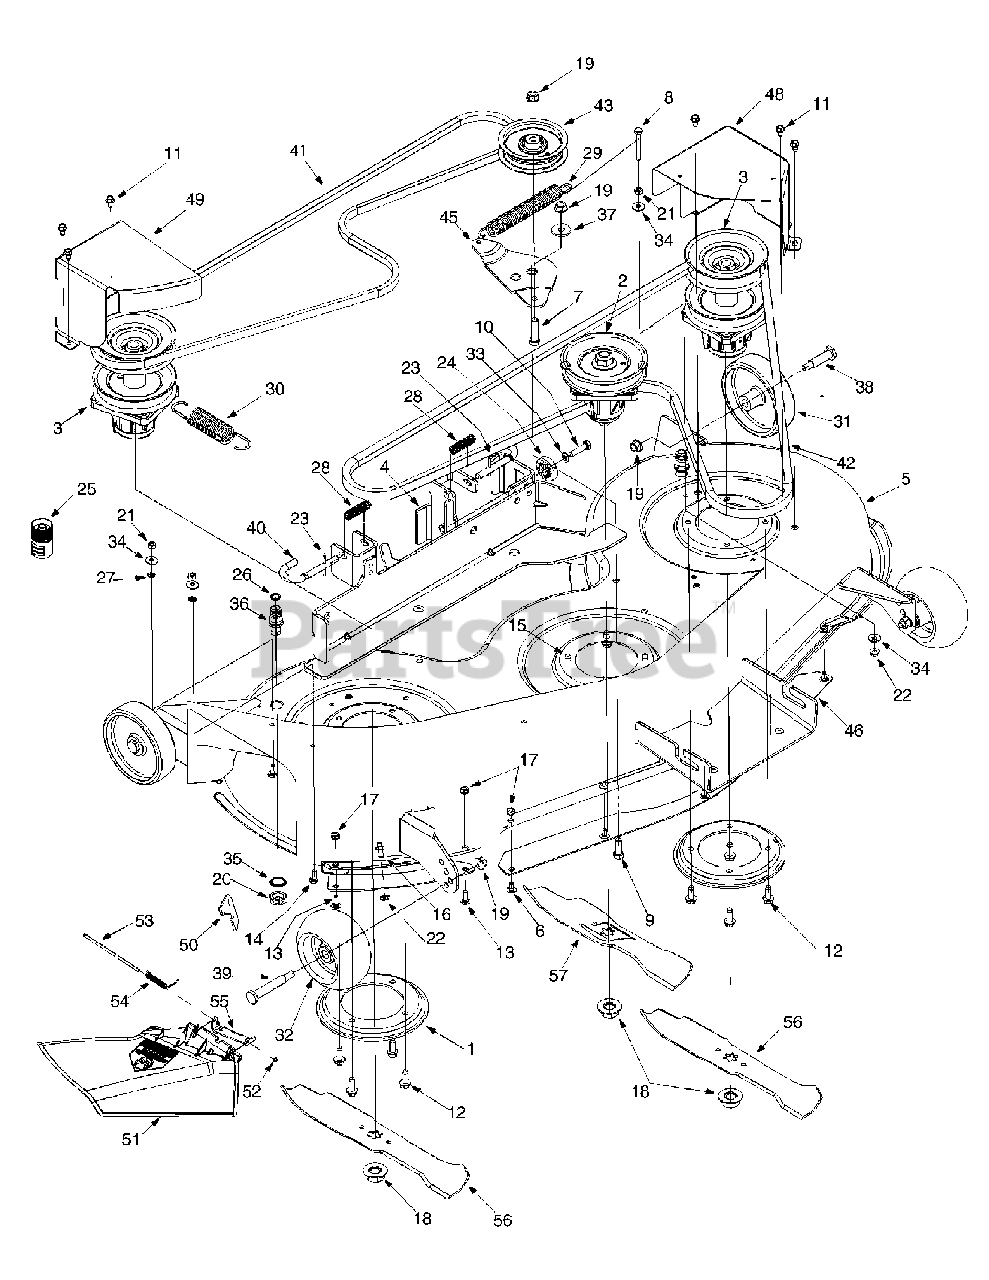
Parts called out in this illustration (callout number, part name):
1	Spindle Reinforcement Plate
2	Spindle Assembly, 5.0 Dia.
2	Pulley Only
3	Double Pulley Spindle Assembly
3	Double Pulley Only
5	46-inch Deck Assembly
6	Carriage Screw, 1/4-20 x .50
7	Hex Cap Screw, 3/8-16 x 1.5
8	Hex Cap Screw, 1/4-20 x 2.0
9	Hex Cap Screw, 3/8-16 x 1.0
10	Hex Cap Screw, 5/8-18 x 1.25
11	Self-tapping Screw,1/4-20 x .5
12	Self-tapping Screw,15/16-18 x .875
13	Hex Screw, 1/4-20 x .75
14	Hex Cap Screw, 1/4-20 x .62
15	Self-tapping Screw, 5/16-18 x .75
16	Grasscatcher Pin
17	Hex Sems Nut, 1/4-20
18	Hex Flange Nut, 5/8-18
19	Flange Lock Nut, 3/8-16
20	Hex Nut M16
21	Hex Nut, 1/4-20
22	Hex Flange Lock Nut, 1/4-20
23	Cotter Pin, 1/8 x 1.25
24	Deck Adjustment Gear
25	Nozzle Adapter
26	O-Ring Seal, 16mm x 11mm
27	Push Nut. .25 x .5
28	Compression Spring, .406 x .531 x 1.75
29	Extension Spring, .91 x 7.3
30	Extension Spring
31	Deck Wheel
32	Deck Wheel
33	Lock Washer, 5/16
34	Bell Washer, .265 x .75 x .062
35	Lock Washer
36	Nozzle: Deck Wash-Out System
37	Shoulder Spacer, .625 x 1.16
38	Shoulder Screw
39	Shoulder Screw
40	Deck Release Pin
41	Deck Belt, Poly
43	Idler Pulley, 3.5
45	Idler Bracket
46	Center Deck Skirt (Long)
46	RH Deck Skirt (Short)
48	LH Belt Cover
49	RH Belt Cover
50	Chute Stop
51	Chute Deflector: Side Discharge
52	Speed Nut
53	Hinge Pin
54	Mounting Bracket
55	Torsion Spring
56	Blade: 16.28" Star
57	Blade: 14.88" Star
